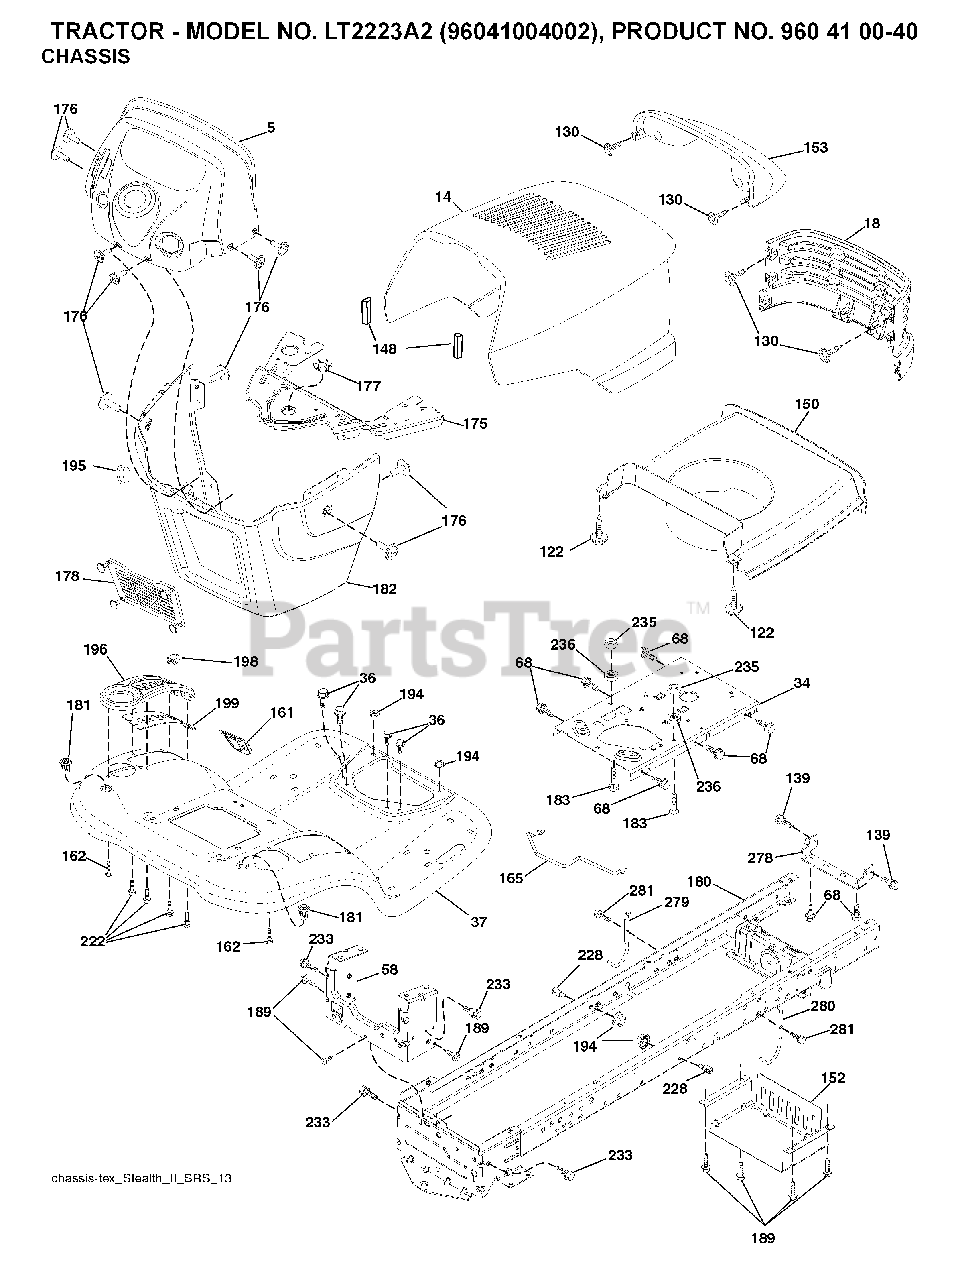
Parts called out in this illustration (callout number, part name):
5	DASH.UPR.STEALTH
34	PLATE.ENGINE.WELDED.CHASSIS
36	SCREW 5/16"
58	DRAWBAR.UPPER.2PC,LRG.FENDER
122	SCREW.WSHD.HEX10-32X5/8
130	SCREW.#10 X 0.750.BOS THREAD
139	BOLT, SHOULDER 5/16-18
148	EXTRUSION BUMPER
150	DUCT HOOD
152	SHIELD BROWNING
161	CONSOLE.FUEL.WINDOW.STGT.BLACK
162	SCREW.HI-LO.CONSOLE
165	SUPPORT.TANK.REAR.W/TE
175	CROSSMEMBER.
176	SCREW.#10-24X5/8.RN.QU
177	BUSHING,STEERING
178	CARGO.ASM.NET.DASH.LOWER
180	CHASS.WLDMNT.TL.12GA/2P.48/54
181	FEND/FTRST.PCH.CPH.NFW
182	DASH.LOWER.
183	BOLT.5/16-18X1-1/4 FULL.THREAD
189	SCREW
194	NUT LOCK HEX FLANGE 5/16-18
195	PLUG.HOLE.DASH.LOWER.12V.BLK
198	INDICATOR DECK LIFT
199	PLATE DECK LIFT
222	SCREW.1/4-20X5/8
228	STUD.FASTNER.W/ANTI-ROTATE
233	BOLT.SHOULDER
235	SPACER FENDER
236	NUT.CENTERLOCK.5/16-
278	BRKT.HOOD/MUFF.STEALTH
